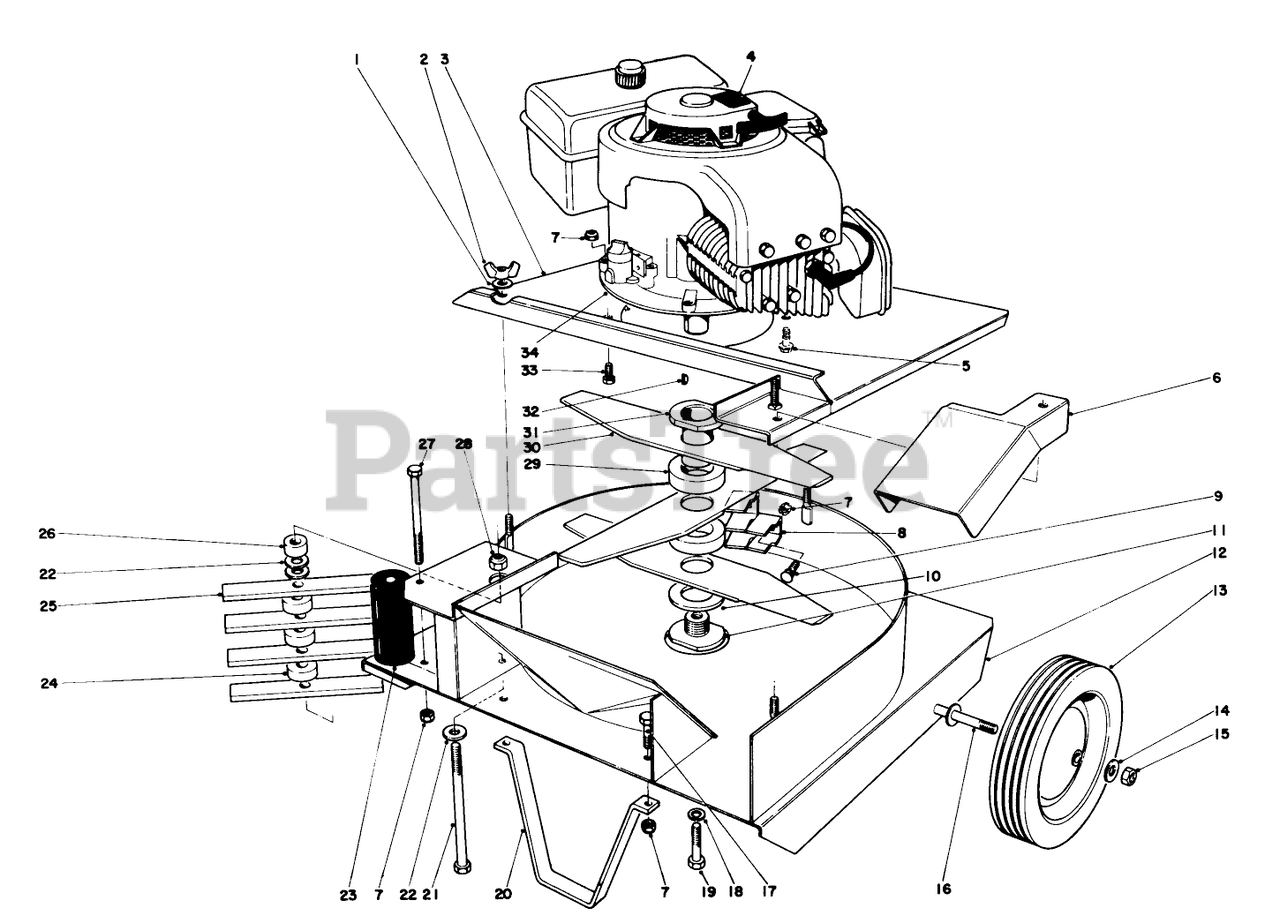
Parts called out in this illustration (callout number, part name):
1	WASHER-FLAT
2	NUT-WING
3	Engine Base W.A.
4	Caution Decal
5	SCREW-HWHTF
6	Deflector
7	NUT-LOCK, CONE
8	Secondary Finger
9	BOLT-CARR
10	Blade Spacer
11	Hub Keeper
13	Wheel
14	WASHER-FLAT
15	1/2-13 CONELOCK NUT
17	SCREW-HH
18	WASHER-LOCK/SP
19	Capscrew
20	Leg Stand
21	Special Screw
22	WASHER-FLAT
23	Shock Absorber
24	Lower Finger Spacer
25	Primary Finger
26	SPACER-FINGER
27	SCREW-HH
28	NUT-LOCK, NI
29	Hub Spacer
30	Blade
32	KEY-WOODRUFF
33	SCREW-HH
34	Engine
